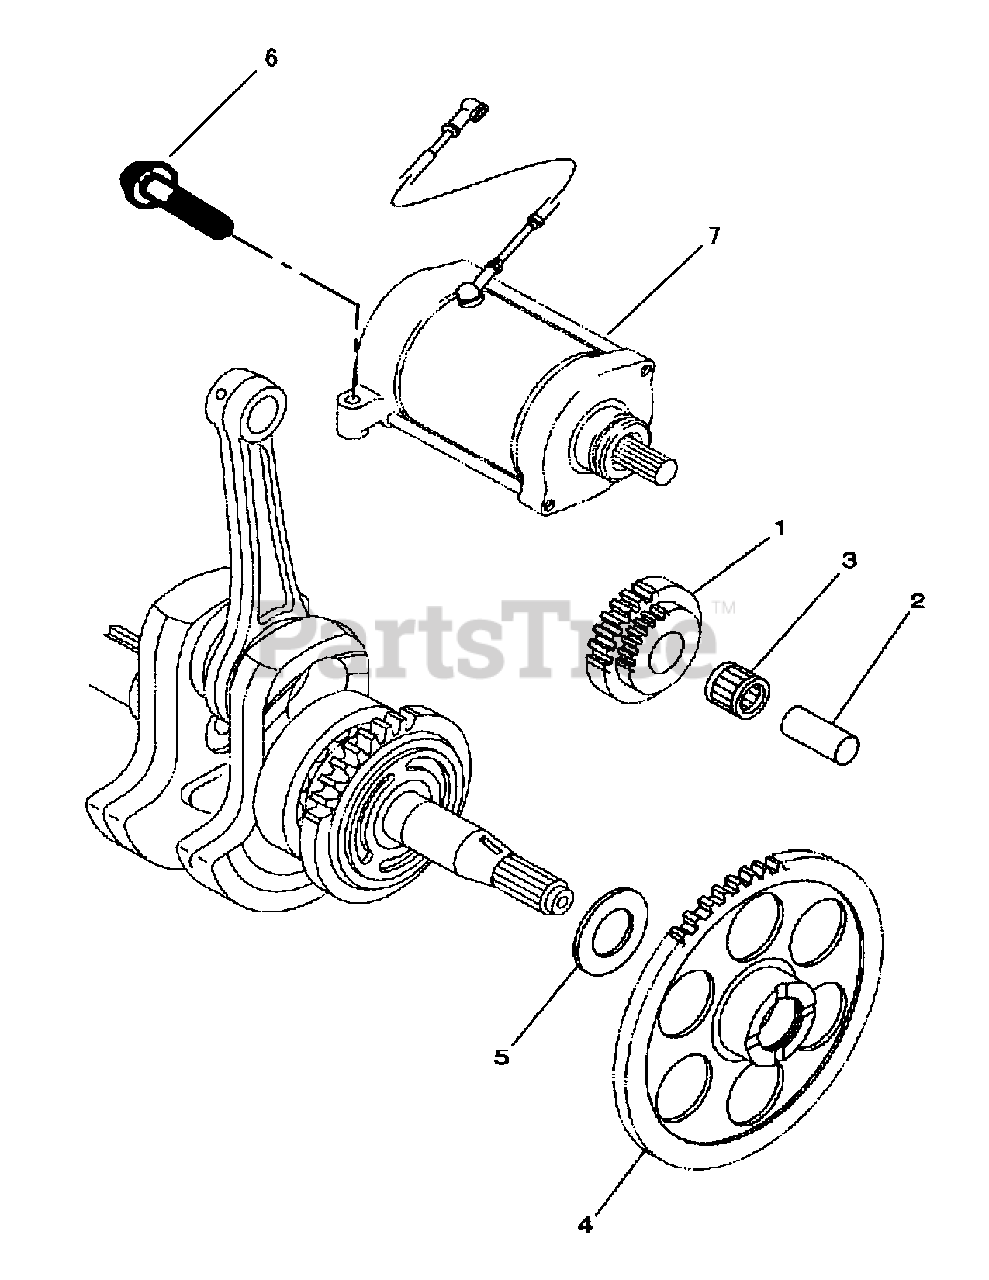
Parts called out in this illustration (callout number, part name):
1	Gear Wheel-Pair
2	Gear Wheel Shaft-P
3	Needle Bearing KBK121618
5	Washer 25×39×1
6	Flangebolt M6X30
7	Starter-UTV Comp
